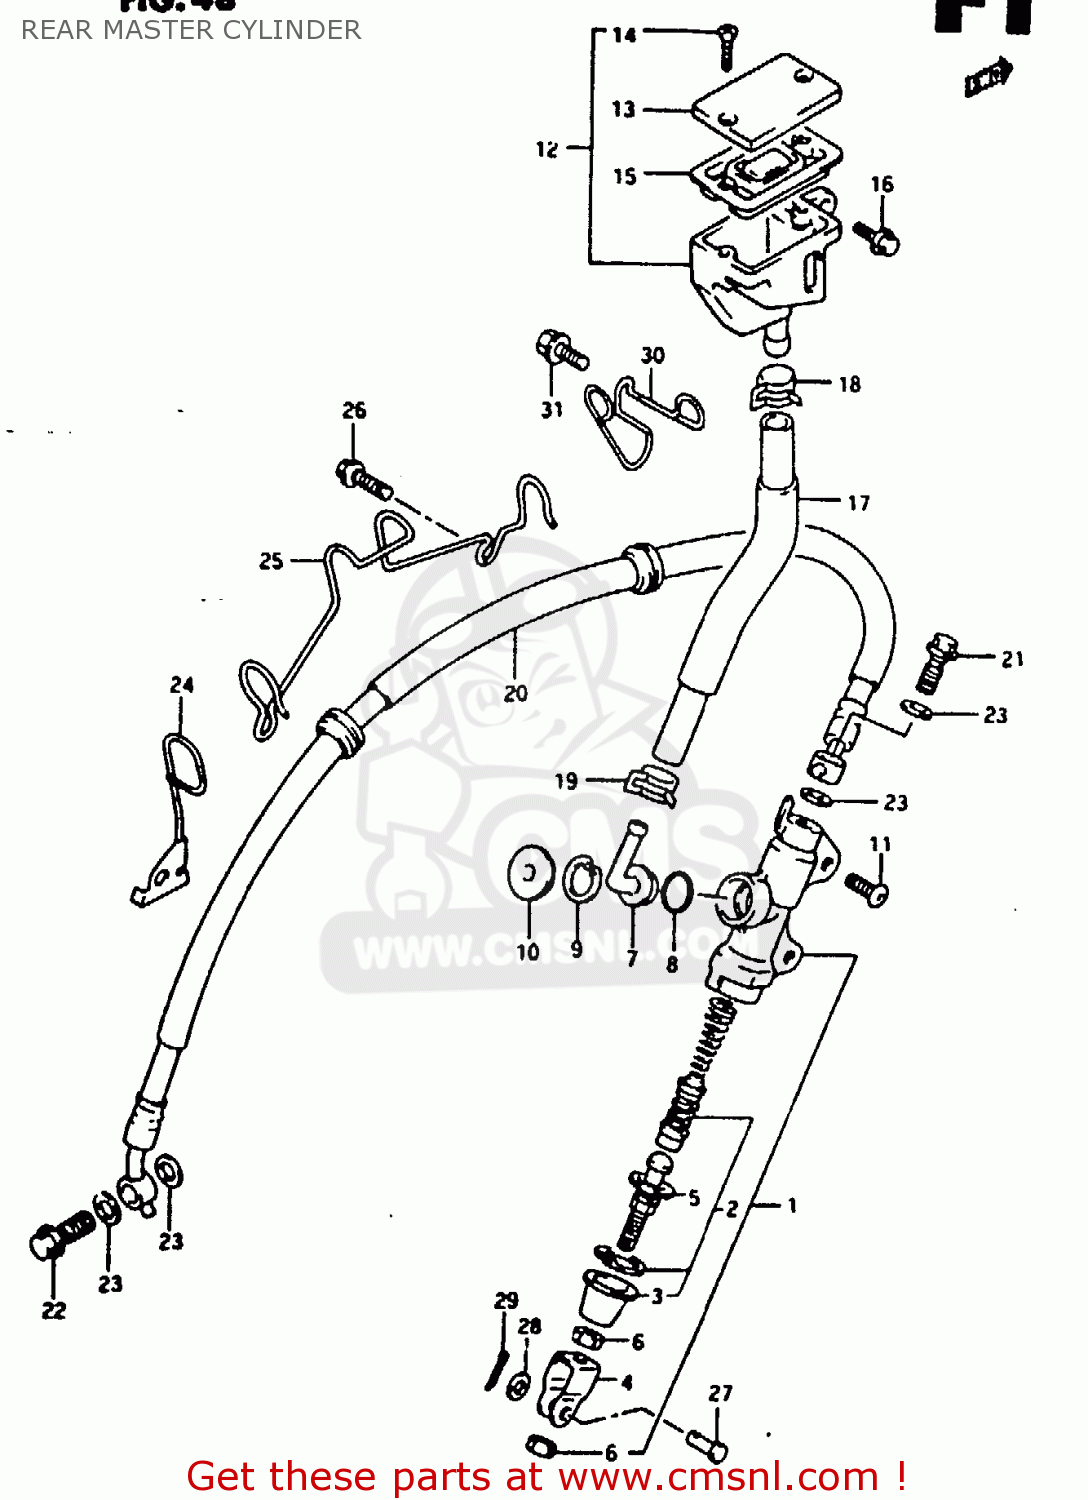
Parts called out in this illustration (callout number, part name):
1	CYLINDER ASSY, REAR MASTER
2	PISTON/CUP SET
3	BOOT
4	YOKE
5	ROD,PUSH
6	NUT
7	CONNECTOR
8	O RING
9	CIRCLIP
10	COVER,DUST
11	BOLT(8X20)
12	TANK ASSY,RR RESERVOIR
13	CAP
14	SCREW
15	DIAPHRAGM
16	BOLT
17	HOSE,RESERVOIR TANK
18	CLIP
19	CLIP
20	HOSE,RR BRAKE
21	BOLT UNION
22	BOLT UNION
23	WASHER(10X15X1.5)
24	GUIDE, BRAKE HOSE
25	CLAMP,RR BRAKE HOSE
26	BOLT
27	PIN
28	WASHER
29	PIN
30	GUIDE, RESERVOIR TANK HOSE
31	BOLT
